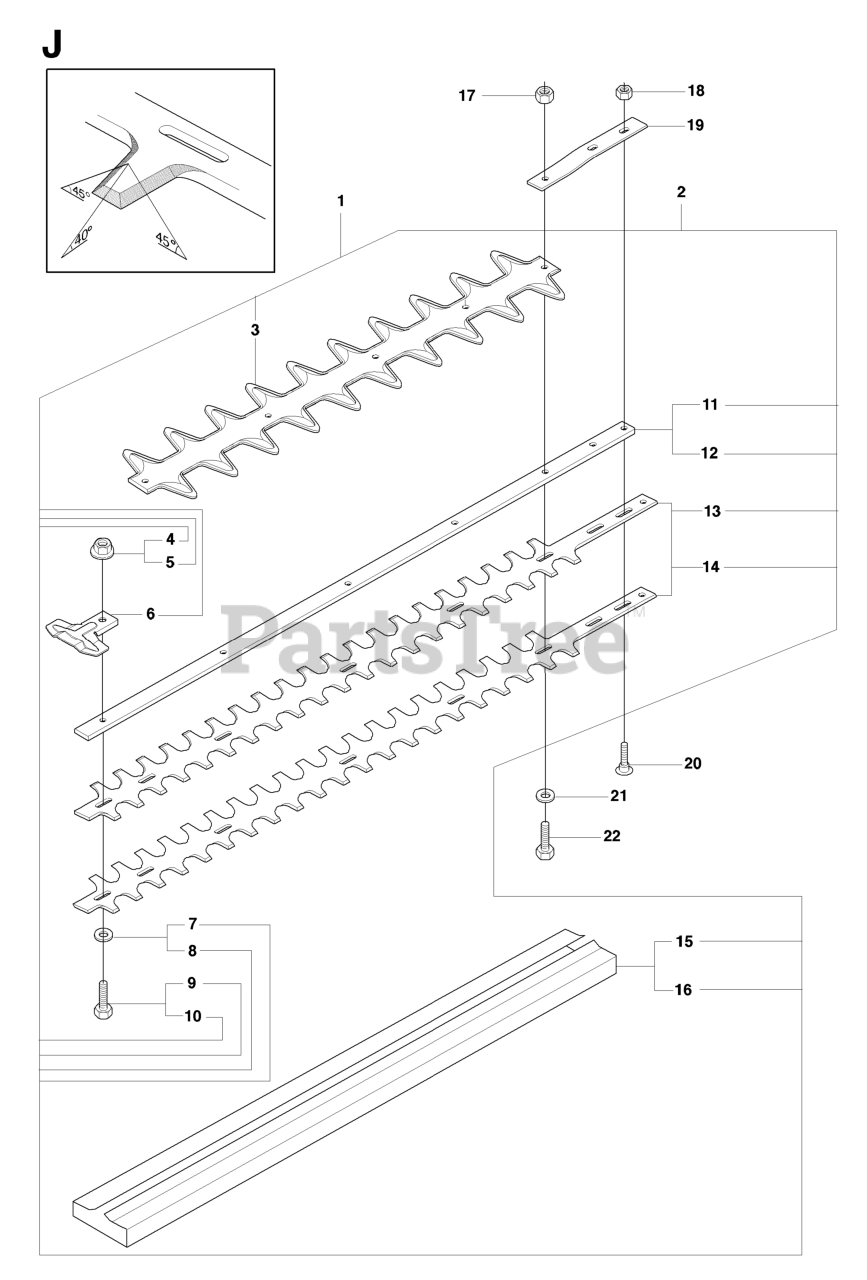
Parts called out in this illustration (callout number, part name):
1	BLADE
2	CUTTER ASSY
4	NUT
5	NUT
7	WASHER 6,4X18X1,5
8	WASHER 6,4X18X1,5
9	SCREW
10	SCREW
11	PLATE
12	BALK
13	BLADE
14	BLADE
15	PROTECTOR
16	PROTECTOR
18	NUT
21	WASHER 6,4X18X1,5
